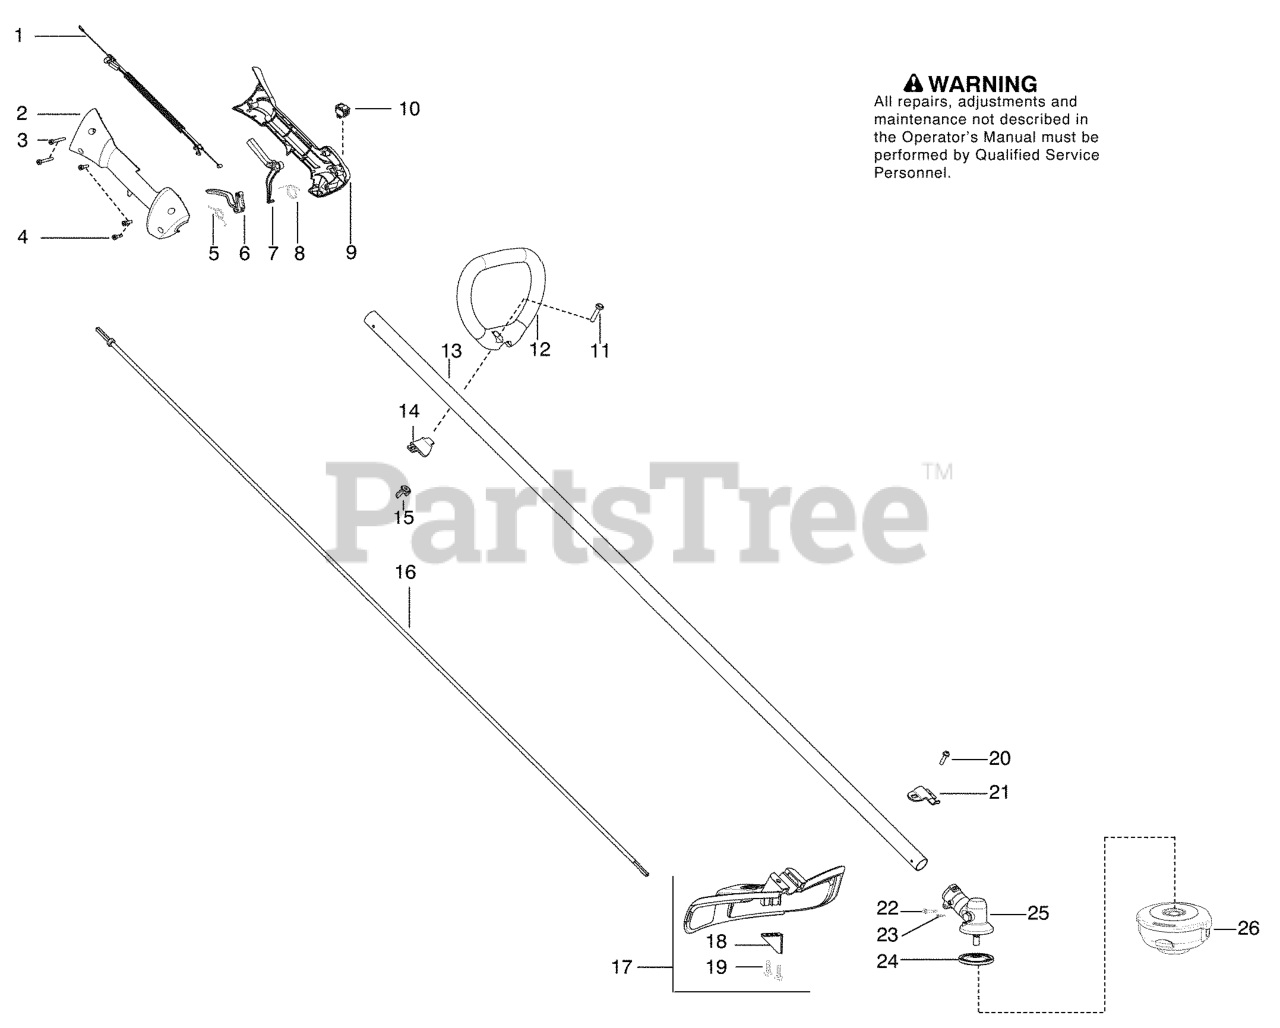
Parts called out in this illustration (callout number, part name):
1	Assy-Cable/Wire Harness
2	HOUSING-THROTTLE RH
4	SCREW M4 X 1.75 PT 16MM
5	SPRING TRIGGER
6	TRIGGER THROTTLE
7	THROTTLE LOCKOUT
8	SPRING LOCKOUT
9	HSG THROTTLE LH
10	KIT SWITCH
11	BOLT, TYPE 2
13	KIT DRIVESHAFT SST
14	CLAMP ASSIST HANDLE
15	WINGNUT, TYPE 2
16	Flex shaft
17	KIT COBI SHIELD
18	Limiter-Line
20	SCREW 1/4-20 X 7/8 (TAP
21	BRACKET SHIELD STRAIGHT SHAFT
22	SCREW - CARB. ADAPTOR
24	DRIVE DISC
25	ASSY GEARBOX
26	T25 10MM LH TRIMMER HEAD
